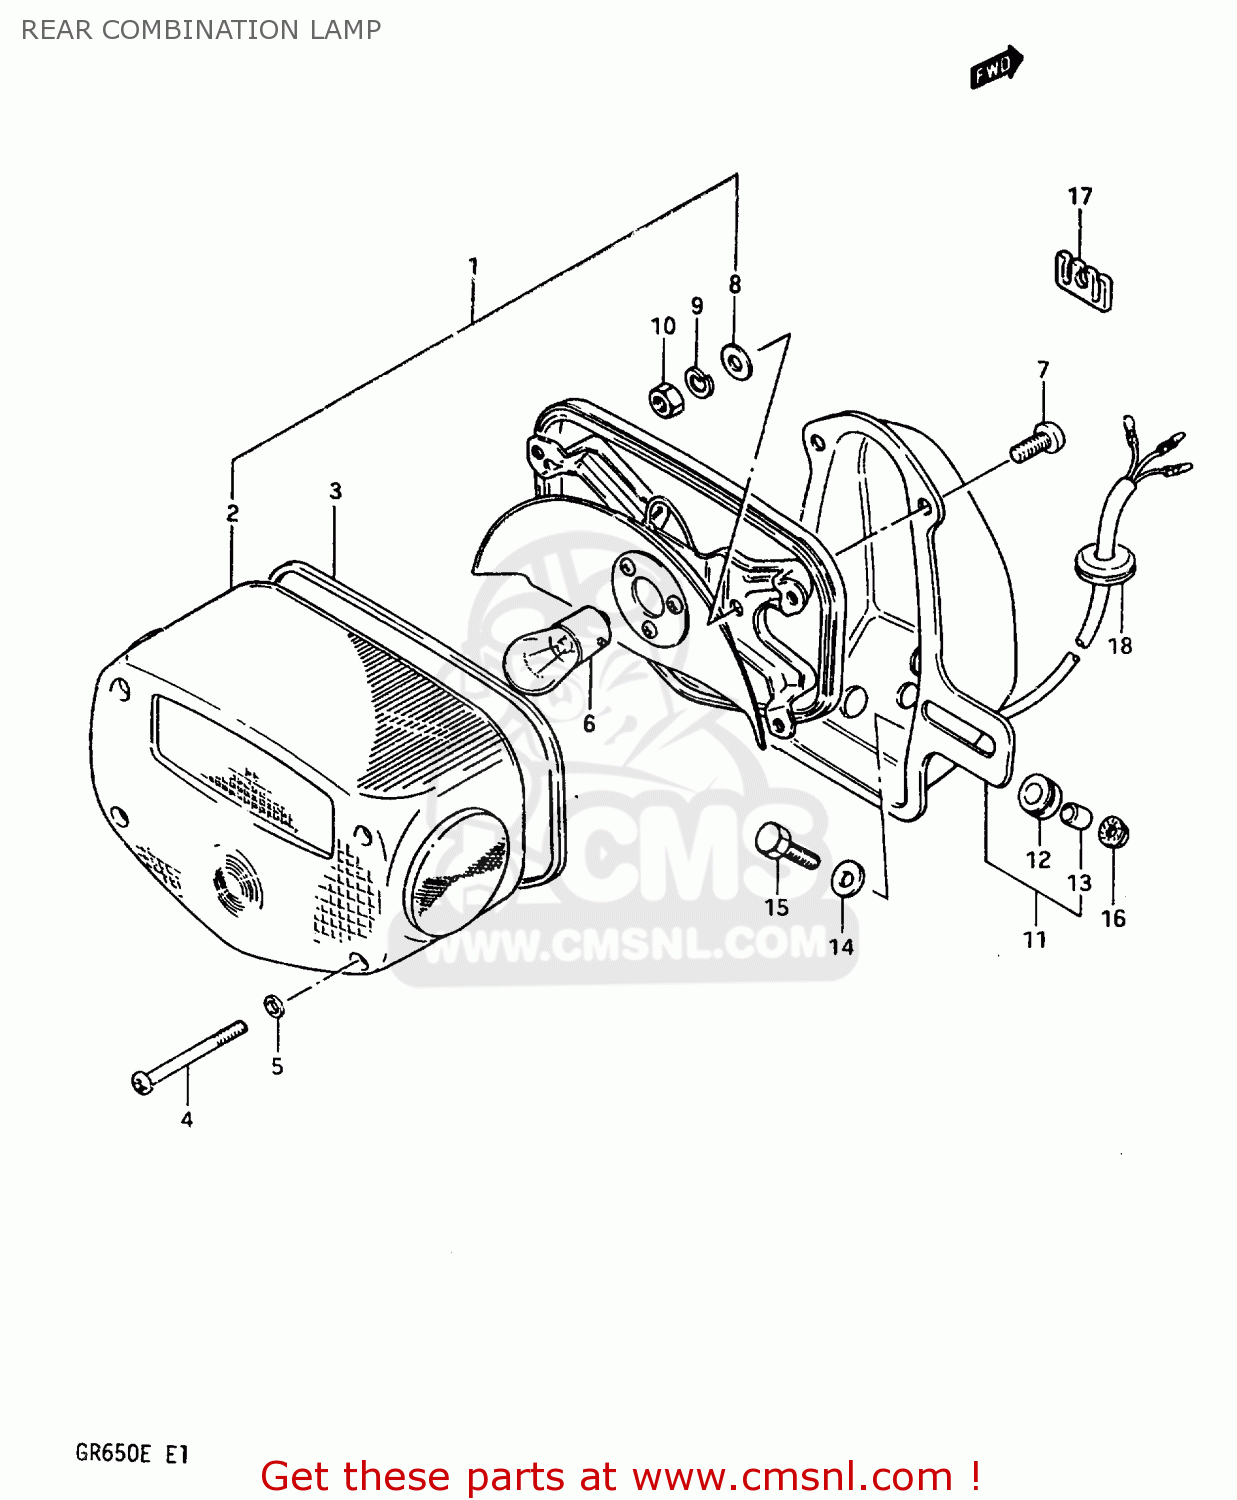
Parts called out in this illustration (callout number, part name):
1	LAMP UNIT, REAR COMBINATION
2	LENS
3	GASKET (NAS)
4	SCREW (4X55)
5	GASKET (NAS)
6	BULB(12V23W)
7	SCREW 6X12
8	WASHER
9	LOCK WASHER
10	NUT
11	BRACKET UNIT,TAIL LAMP
12	CUSHION
13	SPACER
14	WASHER (6.5X20X1.2)
15	BOLT
16	NUT 6MM
17	GUIDE,WIRING HARNESS
18	GROMMET
